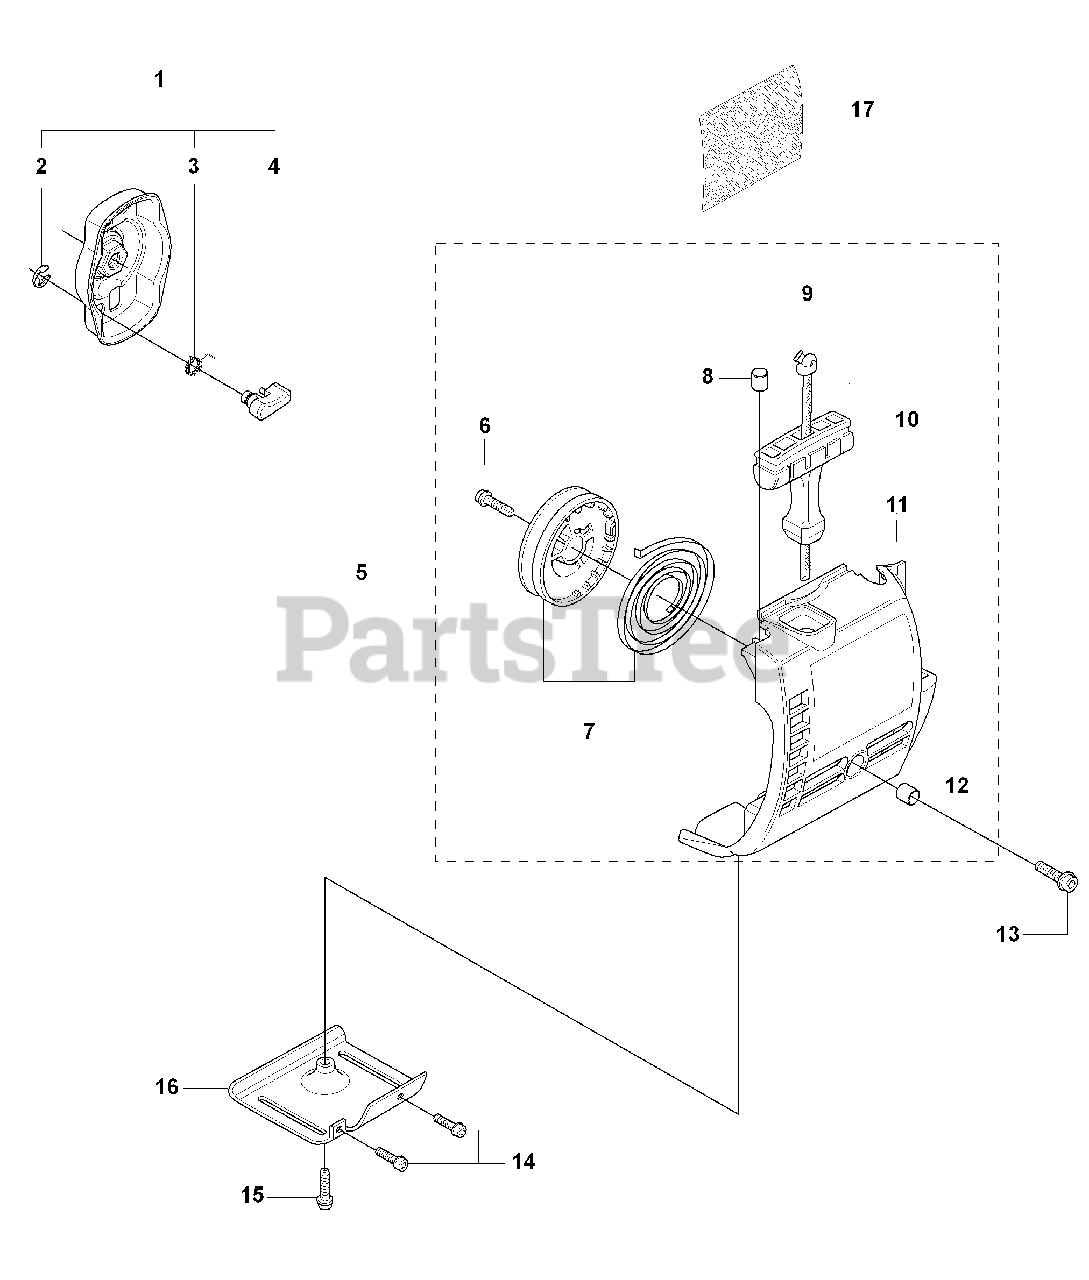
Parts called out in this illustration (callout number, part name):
1	STARTER PAWL BRIDGE
4	STARTER PAWL
5	%STARTER ASSY
7	STARTER PULLEY ASSY.
8	SPACING SLEEVE
9	STARTER ROPE
10	STARTER HANDLE
11	RP STARTER HOUSING
12	SPACING SLEEVE
13	SCREW
15	SCREW
